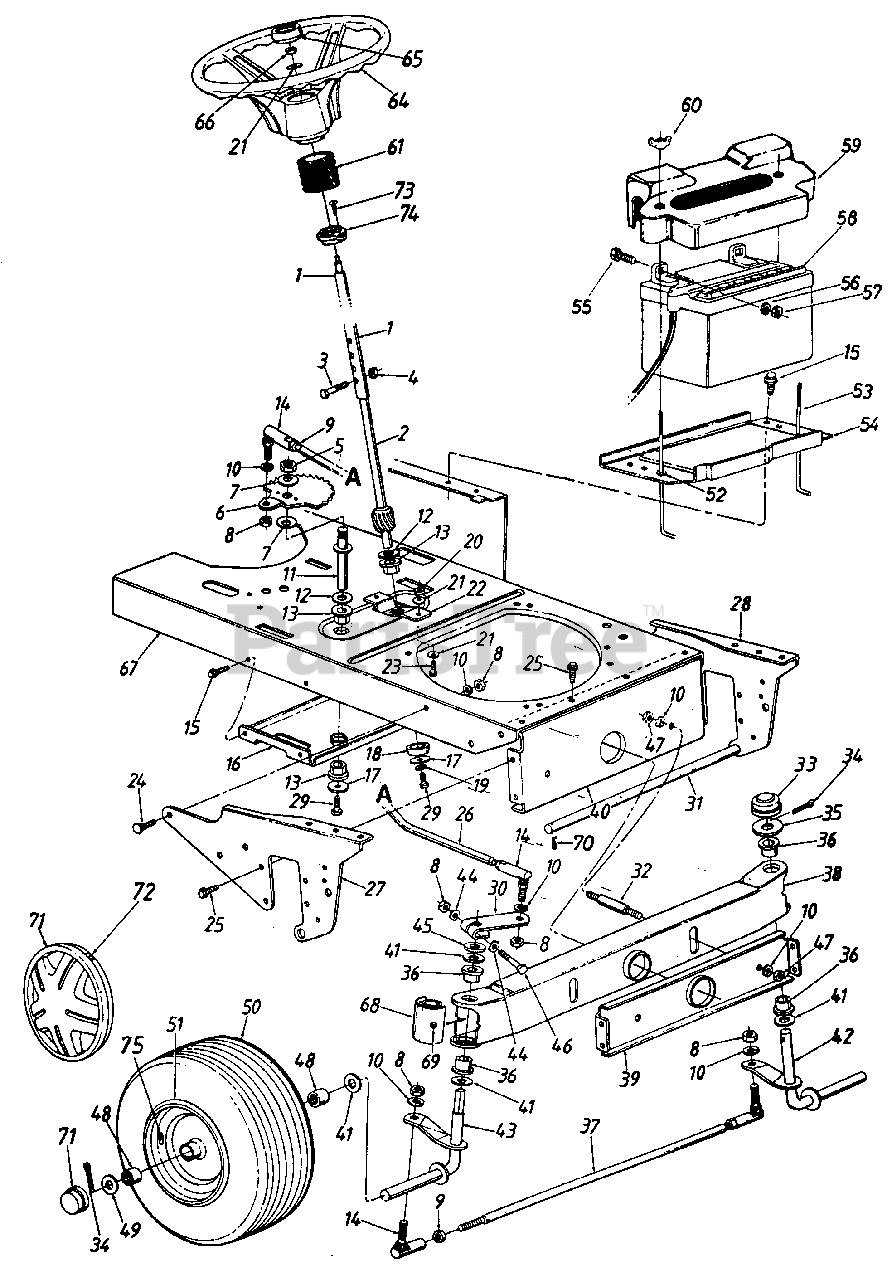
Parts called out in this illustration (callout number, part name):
1	Steering Column Ass'y.
2	Lower Steering Shaft
3	Hex Bolt 1/4-20 x 1.31" Lg.
4	Hex L-Nut 1/4-20 Thd.
5	Hex Nut 5/8-18 Thd.
6	Steering Gear Segment
7	Bell-Wash. 518" I.D. x 1.25" O.D.
8	Hex Nut 3/8-24 Thd.
9	Hex Jam Nut 3/8-24 Thd.
10	L-Wash. 3/8" I.D.
11	Steering Gear Segment Shaft
12	Fl-Wash. .64" I.D. x 1.24" O.D.
13	Hex Flange Brg. .63" I.D.
14	Ball Joint Ass'y.
15	Hex Wash. Hd. TT-Tap Scr. 1/4-20 x .5" Lg.
16	Deck Idler Support Brkt.
17	Fl-Wash. .33" I.D. x 1.25" O.D.
18	Spacer .985" I.D. x 1.25" O.D.
19	L-Wash. 5/16" I.D.
20	Hex Nut 5/16-24 Thd.
21	Bell-Wash. .345" I.D. x .88" O.D.
24	Ribbed Neck Bolt 3/8-24 x .8" Lg.
25	Hex Wash. TT-Tap Scr. 5/16-18 x .62" Lg.
26	Steering Drag Link
27	Pivot Bar Side Plate-R.H.
28	Pivot Bar Side Plate-L.H.
29	Hex Bolt 5/16-18 x .62" Lg.
30	Steering Arm
31	Deck Connecting Rod
32	Pivot Bar Shld. Bolt 3/8-16 x 518" Lg.
33	Cap
34	Cotter Pin 5132" Dia.
35	Flat Washer
36	Flange Brg. .757" I.D.
37	Tie Rod 20.25" Lg.
38	Pivot Bar Assy.
41	Fl-Wash. .76" I.D. x 1.49" O.D.
42	Front Axle Ass'y.-L.H.
43	Front Axle Ass'y.-R . H .
44	Bowed Washer
45	Spacer .755" I.D. x 1.25" O.D.
46	Hex Bolt 3/8-24 x 2.25" Lg.
47	Hex Nut 3/8-16 Thd.
48	Flange Brg. .75" I.D.
49	Fl-Wash. .71" I.D. x 1.5" O.D.
51	Rim Only
52	Push Nut
53	Battery Hold Down Rod
54	Battery Plate
56	L-Wash. 1/4" I.D.
57	Hex Nut 1/4-20 Thd.
58	Battery
59	Battery Cover
60	Wing Nut Plastic 1/4-20 Thd.
61	Steering Bellow
64	Steering Wheel
65	Steering Wheel Cap
66	Hex L-Nut 5/16-24 Thd.
67	Lower Frame
68	Pivot Bar End Cap
69	Grease Fitting
70	Internal Cotter Pin
71	Hub Cap
72	Spring Clip
73	Oval Hd. Cr.-Sunk Scr. #10 x 518" Lg.
74	Flange Brg. .89" I.D. x 1.36" O.D.
75	Air Valve
